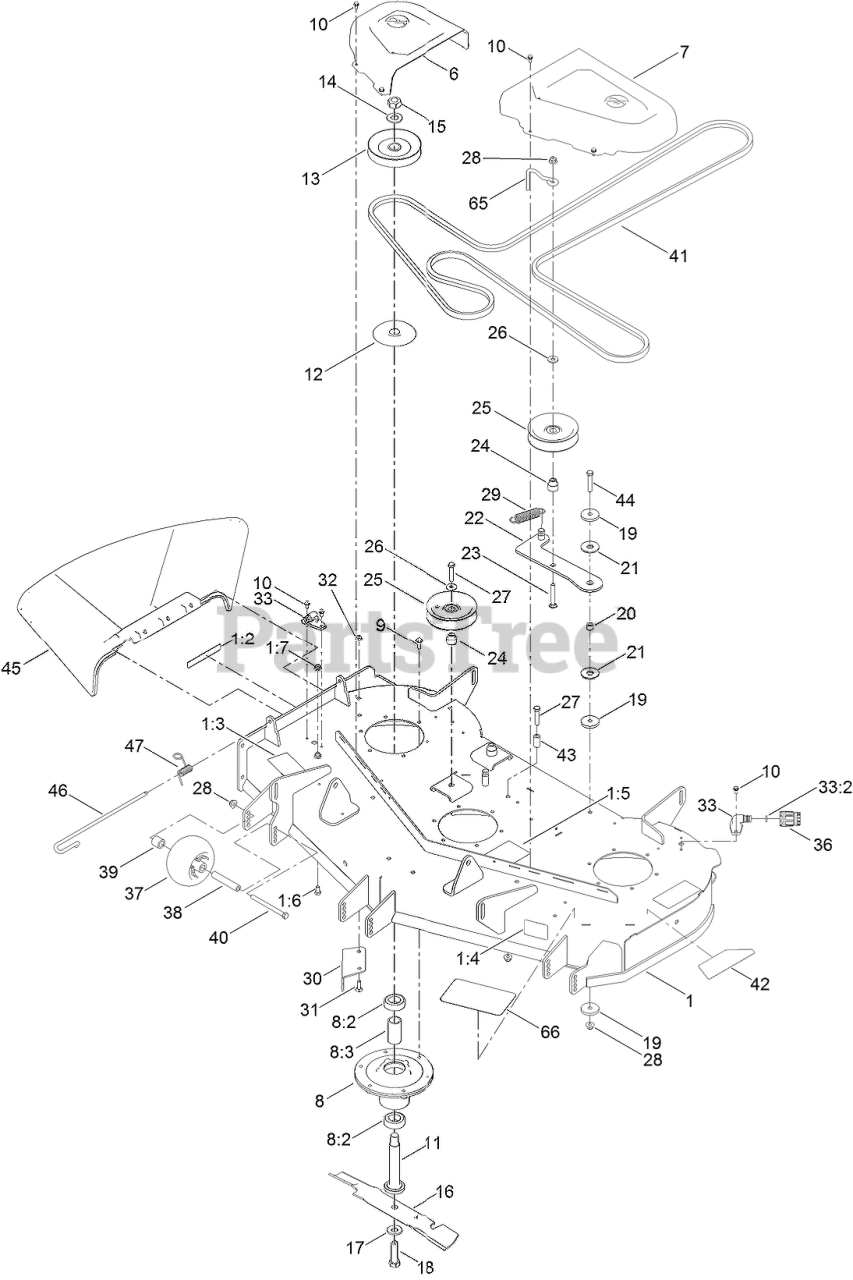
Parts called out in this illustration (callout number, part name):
1	DECK ASM
1:2	DECAL-DANGER
1:3	DECAL-DANGER, DECK
1:4	DECAL-SCALP, ANTI
1:5	DECAL-ROUTING, BELT
1:6	SCREW-HH
1:7	NUT-HF, NI
6	COVER-BELT, RH
7	COVER-BELT, LH
8	SPINDLE ASM
8:2	BEARING-BALL
8:3	SPACER-BEARING
9	SCREW-TAPTITE
10	SCREW-HWH
11	SHAFT-SPINDLE
12	SHIELD-BEARING
13	PULLEY
14	WASHER
15	NUT-HEX
16	BLADE-HI FLO, 16.50 INCH
17	WASHER-BELLEVILLE
18	SCREW-BLADE
19	WASHER-PLAIN
20	BUSHING-LEVER, LIFT
21	WASHER-FRICTION, COMPOSITE
22	ARM-IDLER
23	SCREW-CARR
24	BUSHING-IDLER
25	PULLEY-IDLER, FLAT
26	WASHER-HARDENED
27	SCREW-HH
28	NUT-HF, NI
29	SPRING-EXTENSION
30	BAFFLE-CUTOFF
31	SCREW-CARR
32	NUT-HF, NI
33	FITTING-WASHOUT
33:2	O-RING
36	CONNECTOR-HOSE
37	ROLLER-SCALP, ANTI
38	TUBE-SPANNER
39	SPACER-AXLE, REAR
40	SCREW-HH
41	V-BELT
42	DECAL-DECK
43	SPACER
44	SCREW-HH
45	DEFLECTOR-DISCHARGE
46	PIN-CHUTE
47	SPRING-TORSION
65	GUIDE-BELT, IDLER
66	TREAD-STEP
